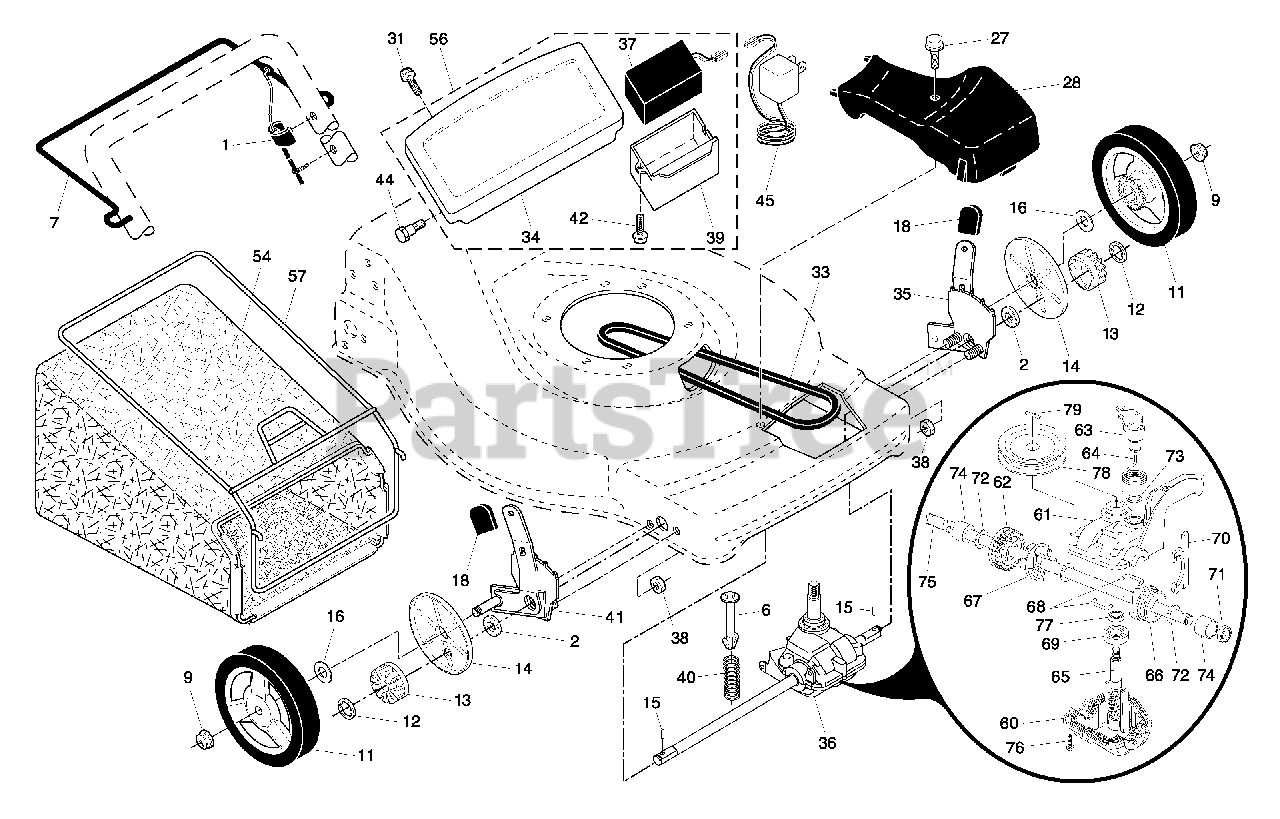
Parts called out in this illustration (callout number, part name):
1	Drive Control Cable
6	Retainer, Spring
7	Bar, Drive Control
9	Locknut, Hex
11	Wheel & Tire Assembly
13	Gear, Pinion
14	Dust Cover
15	Pawl, Drive
16	Washer, Flat 3/8
17	Bearing, Wheel Adjuster
18	Selector Knob
27	Pan Head Tapping Screw #10-24 x 2-3/4
28	Drive Cover
31	Screw, Torx Pan Head #20
33	V-Belt
34	Trimplate
35	Kit, Wheel Adjuster, LH
36	Gear Case Assembly, Complete
37	Battery
38	Locknut, Hex 1/4-20
39	Box, Battery
41	Kit, Wheel Adjuster, RH
42	Screw, Hex Head #13 x 1/2
44	Screw, Shoulder, Hex Head #10-28 x 5/8
45	Charger, Battery
54	Grassbag Assembly
56	Trimplate / Battery / Battery Box Assembly
57	Frame, Grassbag
60	Case, Lower
61	Case, Upper
62	Gear, 27 Teeth
63	Lever, Clutch
64	Spring, Return
65	Shaft, Input
66	Dog, Movable
67	Dog, Fixed
68	Wire, Formed
69	Bearing, Ball
70	Fork, Shift
71	Seal, Output Shaft
73	Seal, Case
75	Shaft, Output
77	Seal, Input Shaft
78	Pulley, Drive
79	Pin, Retainer
